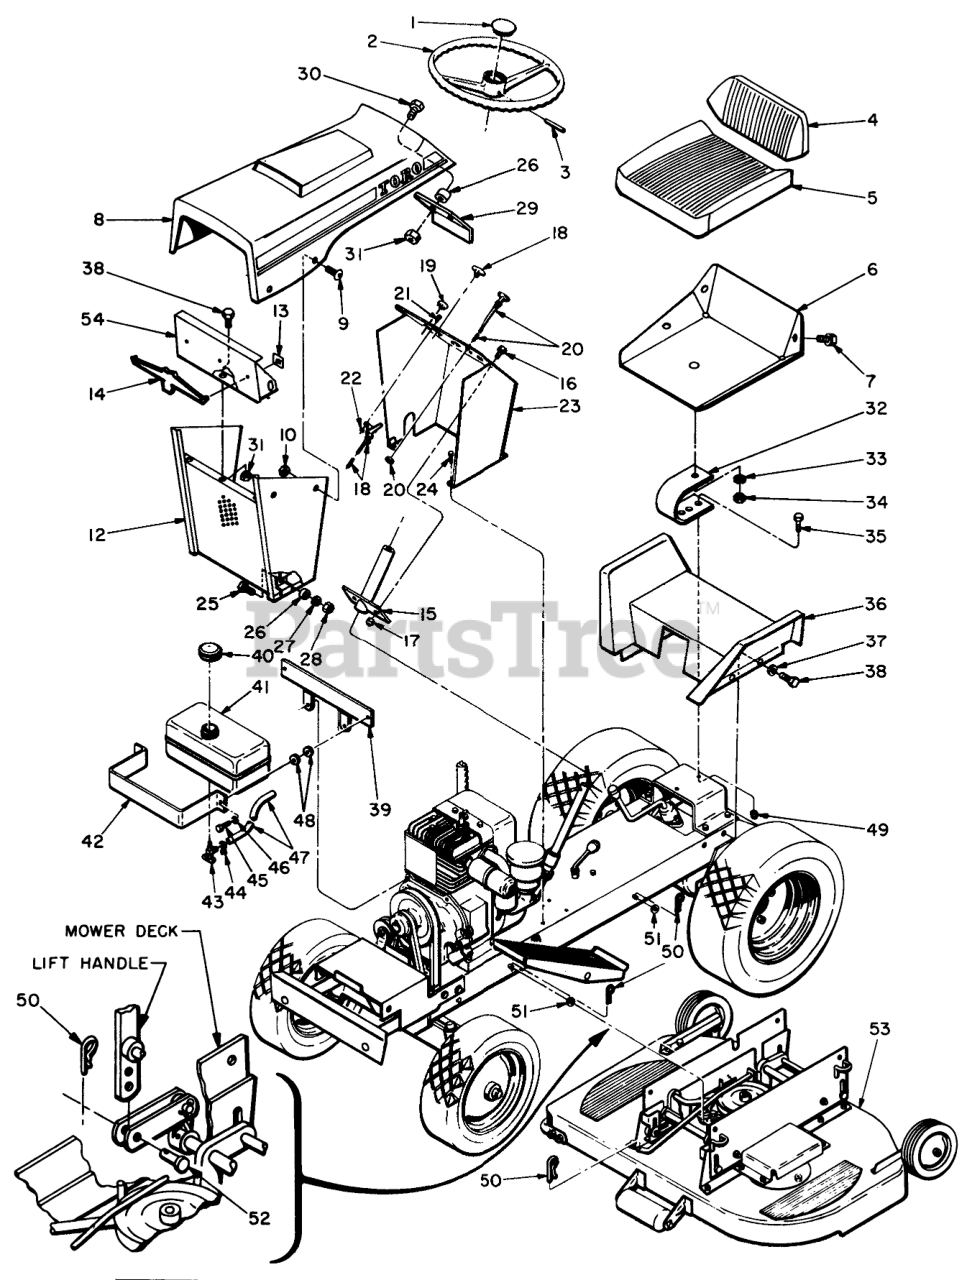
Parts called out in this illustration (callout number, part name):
1	Steering Wheel Cap
2	Steering Wheel
3	Roll Pin
4	Back Cushion
5	Seat Cushion
6	Seat Frame
7	Screw
11	WASHER-FLAT
12	Grille Assy
13	Nut
14	Bullshead
15	Steering Tube Assy
16	BOLT-CARR
18	Throttle Control
19	Plug Button
20	Choke Control
21	Screw
22	NUT-KEPS
23	Control Panel Assy
25	SCREW-HH
26	GRILLE HINGE SPACER
27	WASHER-FLAT
29	Hood Latch
31	Nut
32	Seat Spring
33	WASHER-LOCK
34	NUT-JAM
35	SCREW-HH
36	Fender Assy
37	WASHER-LOCK
38	SCREW-HH
39	Gas Tank Clamp
40	Gas Tank Cap
41	Gas Tank
42	Clamp
43	Shutoff Valve
44	Hose Clamp
45	SCREW-HH
46	WASHER-LOCK
47	Gas Hose
48	Rubber Washer
49	Nut
50	PIN-COTTER, HAIR
51	Washer
52	Pin
53	Mower Housing Group
54	Blank Headlamp
